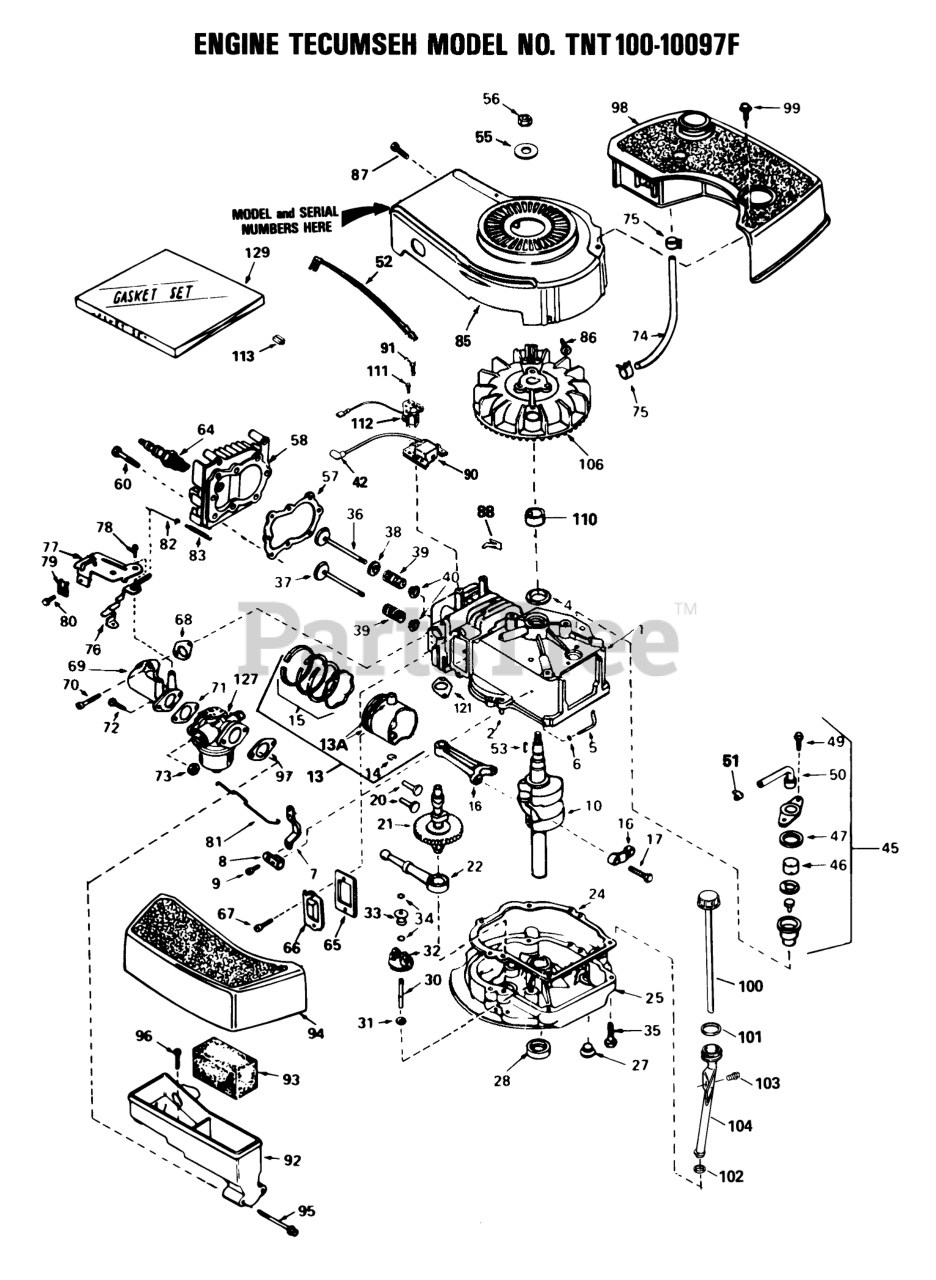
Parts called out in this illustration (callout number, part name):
1	Cylinder Assembly (Incl. Ref. #2 & 4)
2	Pin-Dowel
4	Seal-Oil
5	Rod, Governor (Incl. Ref. #6)
6	Washer-Flat
7	Governor Lever
8	Clamp-Lever, Governor
9	Screw
10	Crankshaft
13	Piston, Pin & Ring Assy. (Std.) (Incl. Ref. #13A, 14 & 15)
13	Piston, Pin & Ring Assembly (.010 oversize) (Incl. Ref. #13A, 14 & 15)
13	Piston, Pin & Ring Assembly (.020 oversize) (Incl. Ref. #13A, 14 & 15)
13A	Piston & Pin Assembly (Std.)(Incl. Ref. #14)
13A	Piston & Pin Assembly (.010 oversize)(Incl. Ref. #14)
13A	Piston & Pin Assembly (.020 oversize)(Incl. Ref. #14)
14	Ring-Retaining, Piston Pin
15	Ring Set-Piston (Std.)
15	Ring Set, Piston(.0100versize)
15	Ring Set (.020" OS)
16	Rod Assembly, Connecting (Incl. Ref. #17)
17	Bolt-Rod, Connecting
20	Lifter-Valve
21	Camshaft(Mech.Comp. Release)
22	Oil Pump ASM
24	Gasket
25	Flange Assembly, Mounting (Incl. Ref. #27, 28 & 30)
27	Plug Oil Drain
28	Seal Oil
30	Shaft-Governor
31	Washer-Flat
32	Gear Assembly, Governor (Incl. Ref. #31)
33	Spool-Governor
34	Ring-Retaining
35	Screw (1/4-20 x 1-1/4)
36	Valve, Intake (Std.)(Incl. Ref. #40)
36	Valve, Intake (-S32n oversize)(Incl. Ref. #40)
37	Valve, Exhaust (Std.)(Incl. Ref. #40)
37	Valve, Exhaust (1/32" oversize)(Incl. Ref. #40)
38	Seal Assy., Intake
39	Spring-Valve
40	Cap-Valve, Spring
42	Cover-Spark Plug
45	Breather Assembly (Incl. Ref. #46thru 51)
46	Element-Breather
47	Gasket-Breather
49	Screw (10-24 x 9/16)
50	Tube, Breaker
51	Clip, Breather
52	Wire-Ground
53	Key-Flywheel
55	Washer-Belleville
56	Nut-Flywheel
57	63573 GIL 42 SNWTHW
58	Head-Cylinder
60	Screw (5/16-18x1-1/2)
64	Spark Plug-Resistor (R J19 L M)
65	Gasket-Breather
66	Cover-Valve
68	Gasket-Intake
69	Pipe, Intake (Incl. Ref. #68)
70	Screw (1/4-20 x 1)
71	Gasket-Carburetor
72	Screw (1/4-28 x 7/8)
73	Nut and Lock Washer (1/4-28)
74	Line-Fuel
75	Clamp-Line, Fuel
76	Lever Control
77	Control Assembly, Speed (Incl. Ref. #76 & 78)
78	Screw, Hex Washer Hd Shoulder Self-Tap
79	Conduit
80	Screw (10-32 x 3/8)
81	Link-Throttle
82	Link Governor Spring
83	Spring Governor
85	Housing-Blower
86	Screw (1/4-20x19/32)
87	Screw (10-24 x 9/16)
88	Clip-Wire
90	Solid State
91	Screw
92	Body Air Cleaner
93	Filer, Air
94	Cove, Air Cleaner
95	Screw Fil Hd.
96	Screw, Hex Washer Hd Shoulder Self-Tap
97	Gasket-Air Cleaner
98	Tank, Fuel (Inc. Ref. #75)
99	Screw (10-32 x 35/64)
100	Dipstick, Oil
103	Screw (10-32 x 1/2)
104	Tube, Oil Fill
106	Flywheel
111	Screw (8-32x27/64)
112	Coil, Alternator
113	Connector-Body
121	Gasket Exhaust
127	Carburetor (Incl. Ref. #71)
129	Gasket Set (Incl. items marked )
